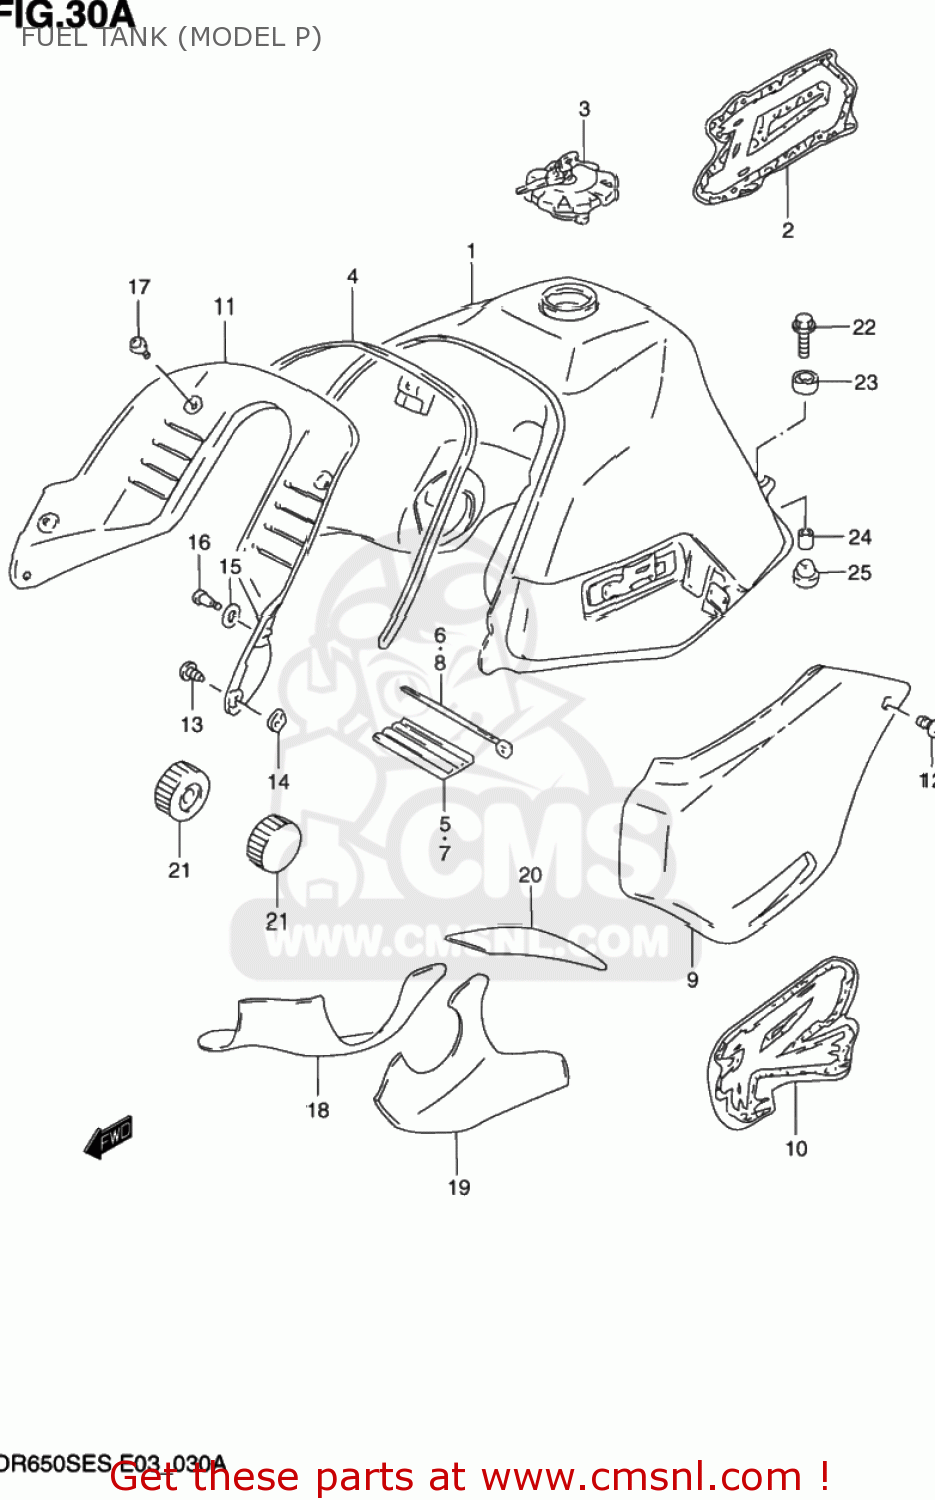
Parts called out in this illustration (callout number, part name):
1	TANK ASSEMBLY,FUEL
2	TAPE SET,FUEL TANK
3	CAP SET,FUEL TANK
4	MOLDING,FUEL TANK
5	CUSHION,FUEL TANK UPR FR
6	CLAMP
7	CUSHION,TANK UPR RR
8	CLAMP(L:300)
9	COVER,FUEL TANK,R
10	EMBLEM,TANK COVER,LEFT
11	COVER,FUEL TANK,FRONT
12	SCREW
13	VIS
14	NUT
15	WASHER (5.1X20X1.4)
16	SCREW(5X18)
17	SCREW, FRONT UPPER
18	SHIELD,FUEL TANK,RIGHT
19	SHIELD,FUEL TANK,LEFT
20	SHIELD,FUEL TANK,CENTER
21	CUSHION,FUEL TANK FR
22	BOLT
23	CUSHION
24	SPACER
25	CUSHION
